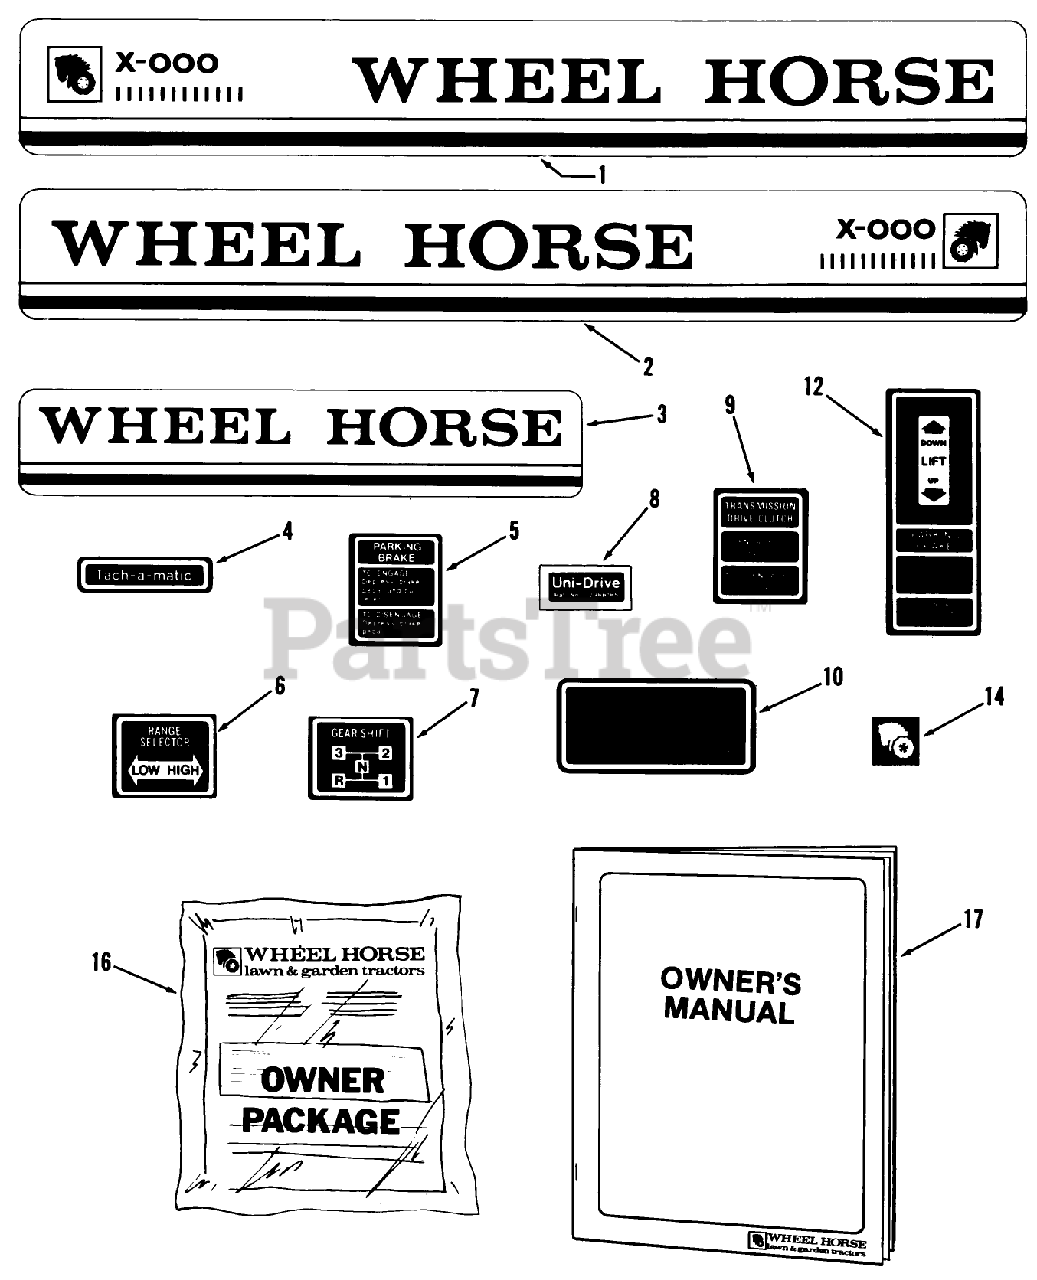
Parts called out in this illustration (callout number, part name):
1	ORDER 101637 R&L DECAL
2	Decal RH C-175 Twin Automatic
2	ORDER 101637 R&L DECAL
3	DECAL-REAR
5	DECAL-PARKING BRAKE
6	DECAL, RANGE SELECTOR
12	Decal-Parking Brake Lift
14	DECAL-LOGO
16	Loose Parts Package C-105, C-125 C-145 Only
16	Loose Parts Package C-175 Twin Only
16	Loose Parts Package C-85 Only
17	Tractor Owner-s Manual (Alternate 810268R1)
